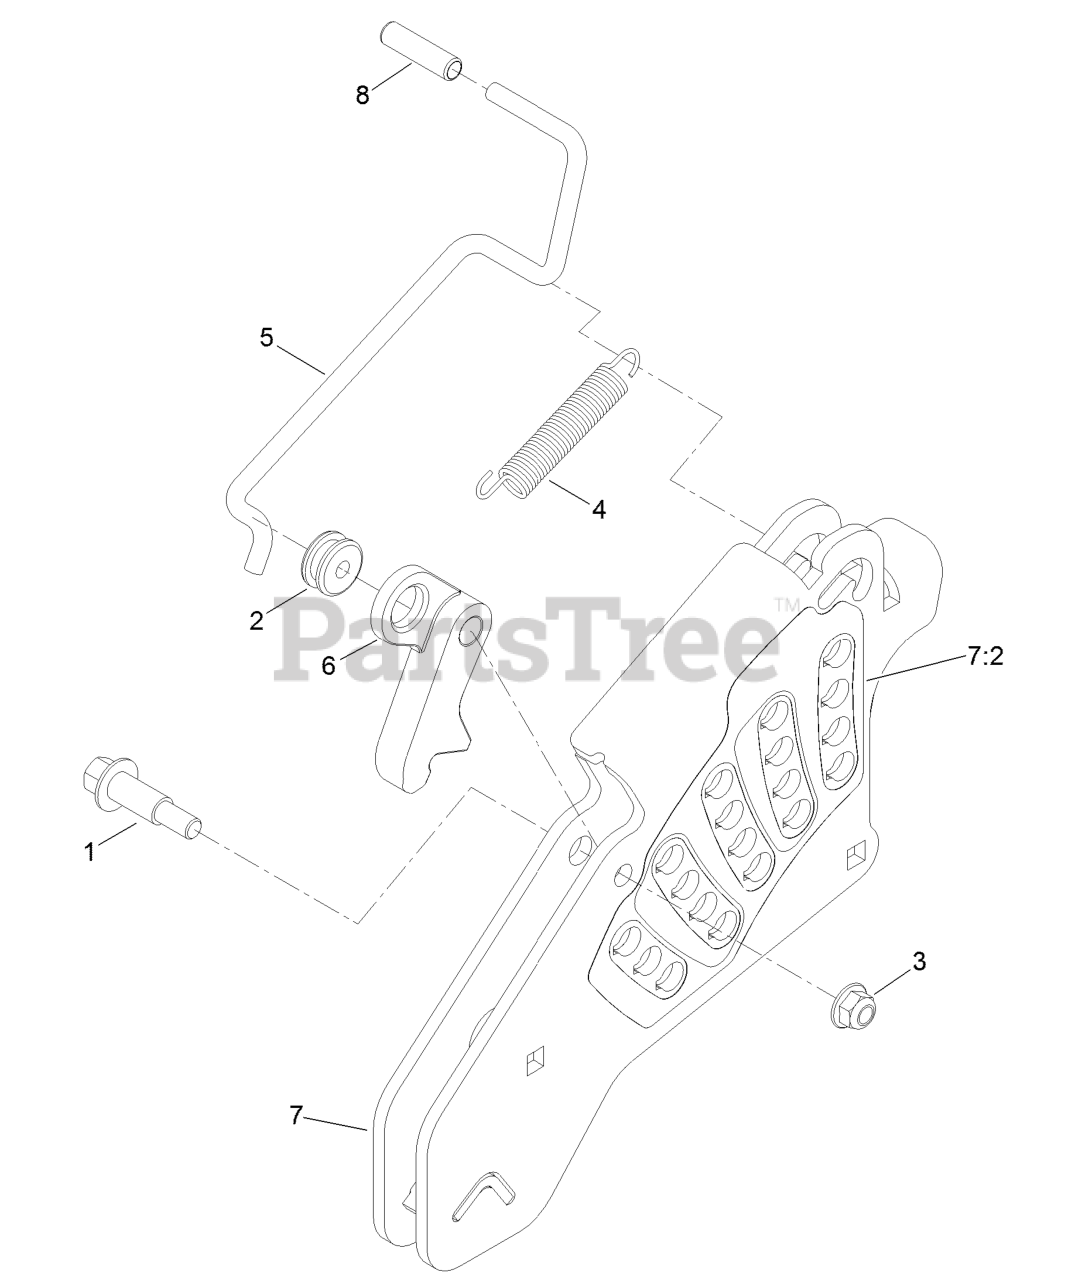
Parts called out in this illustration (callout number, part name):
1	BOLT-SHOULDER
2	GROMMET
3	NUT-HF, NI
4	SPRING-EXTENSION
5	ROD-LOCK, TRANSPORT
6	PAWL-TRANSPORT, HOC
7	HOC PLATE ASM
7:2	DECAL-HOC
8	GRIP-LEVER
